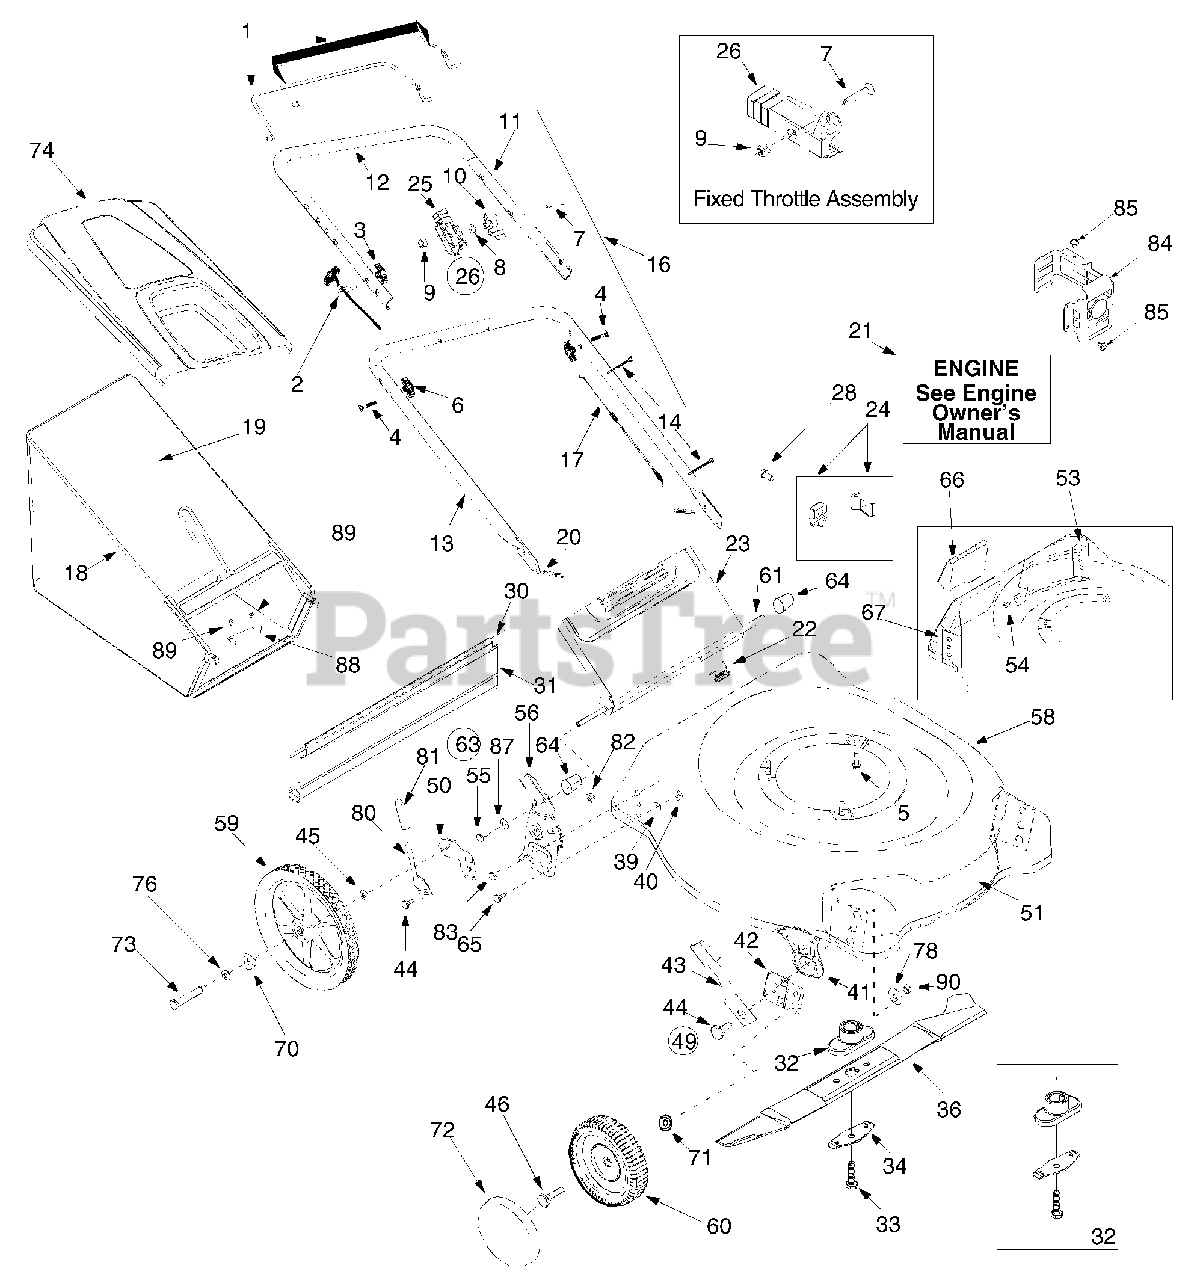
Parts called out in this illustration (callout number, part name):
2	Rope Guide
3	Handle Knob
4	Curved Hd. Bolt 5/16-18 x 2" Lg.
5	Scr. TT. 3/8-16 x 1.00" Lg. Hx Ind Wash.
6	Hand Knob
7	Oval C-Sunk Scr. 1/4-20 x 1.825 Lg.
8	Spring Washer
9	Hex Lock Nut 1/4-20 Thd.
10	Throttle Lever
11	Upper Handle - Grey
12	Foam Grip
13	Lower Handle - Tec. Grey
14	Cable Tie
16	Control Cable - 36"
17	Throttle Control Wire - 55"
19	Grass Catcher Bag w/o Icon
20	Hairpin Clip
21	Engine
22	Door Spring
25	Throttle Body
26	Throttle Box - Complete
28	Hex Wash Hd. Scr. #10-32 x .62 Lg.
30	Wire Rod
31	Rear Flap
32	Blade Adapter Kit
33	Hex Bolt 3/8-24 x 1.5 Lg.
34	Blade Bell Support
36	21" Blade (Std.)
39	Bell Washer .39 I.D. x 1.38 I.D.
40	Hex Nut 3/8-16 Thd.
41	Height Adj. Plate
43	Spring Lever, Front Wheel
44	Shoulder Bolt, .5" Dia. x .357"
45	Bell Wash. .38" I.D. x .88" O.D.
46	Front Axle Bolt
49	Height Adjuster Ass'y Comp. - R.H.
50	Pivot bar - R.H.
54	Torx Mach.Ab-Tap Scr. 1/4-14 x .625. Lg.
55	Scr. TT. 1/4-20 x .500 Hx Ind Wash.
58	Deck - Black
60	Fr. Wheel Ass'y. 8 x 1.75 Slot Bar Grey
61	Chute Door Pivot Rod
63	Handle Bracket Ass'y. - R.H.
64	Spacer .375 O.D. x .50 I.D. x 1.02" Lg
65	Hx Hd Cap Scr. 3/8-16 x .75 Lg.
70	Wave Washer
71	Spring Washer
72	Hub Cap, Radial, Beige
73	Rear Axle Bolt
74	Hardtop Cover w/ Logo
76	Flat Washer
78	Bell Washer
80	Spring Lever, Rear
81	Foam Grip
82	Hex Flange Lock Nut, 3/8-16 Thd.
83	Scr. AB 1/4-14 x .625 Hx Ind Wash.
84	Muffler Guard
85	Screw #10-16 x 3/8" Lg.
87	Bell Washer .265 x .75 x .062
90	Hex Nut 3/8-16 Thd.
